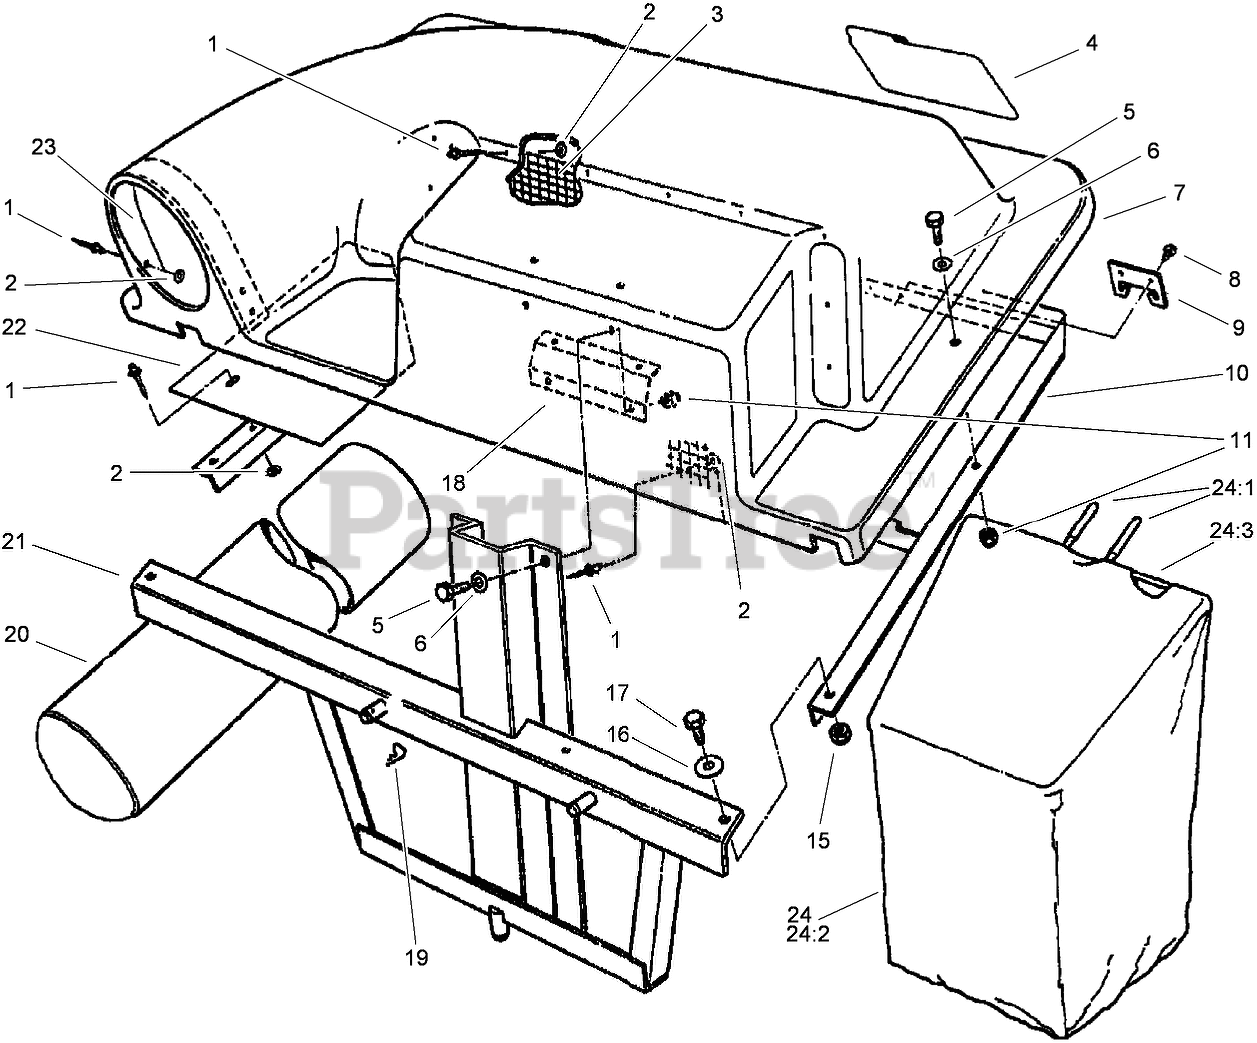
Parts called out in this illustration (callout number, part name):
1	RIVET-POP
2	WASHER-PLAIN
3	SCREEN
4	DECAL-BAGGER, TWIN
5	SCREW-HH
6	WASHER-PLAIN
7	COVER-BAGGER, TWIN
8	SCREW-HWH
9	BRACKET-FRAME, BAG
10	FRAME-COVER
11	NUT-LOCK, NI
15	NUT-LOCK, NI
16	WASHER-FLAT
17	SCREW-HH
18	PLATE-BACKUP
19	PIN-HAIR
20	DUCT-BAGGER
21	FRAME-MOUNTING
23	INLET-SUPPORT
24	BAG ASM
24:1	GRIP-HANDLE, BAG
24:3	FRAME-BAG
